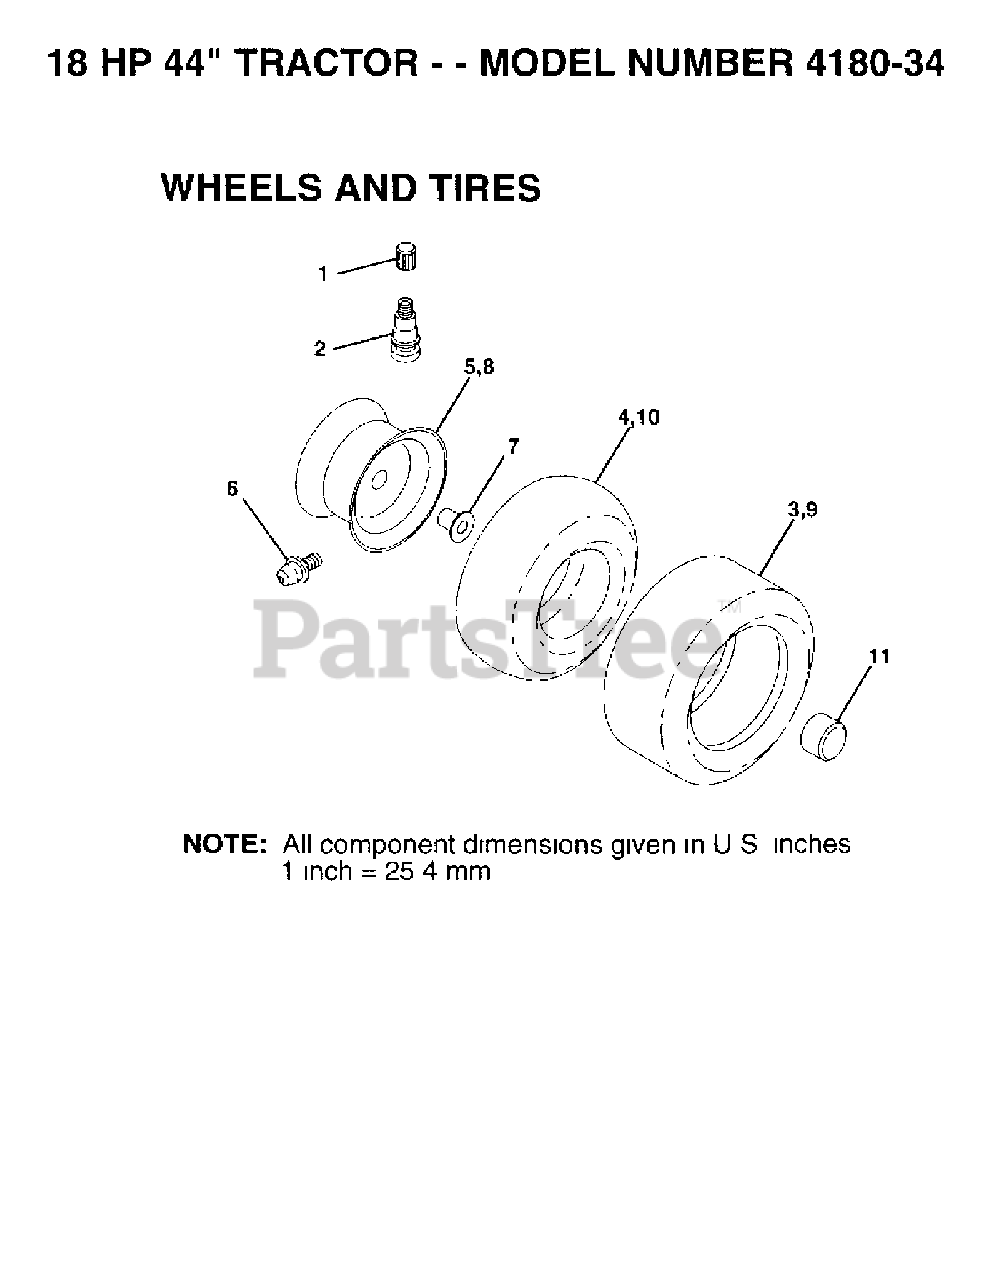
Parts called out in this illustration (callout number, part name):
1	VALVE CAP
2	VALVE STEM LT
3	TIRE HEAVY DUTY
4	TUBE.5.3/4.5/6
5	RIM.ASM.6".FRONT.SILVER
6	FITTING LT
7	BEARING T
9	Tire, .23 X 8.5-12 Turf Saver
10	TUBE.23"X9.5""X12""
11	CAP.HUB.FRONT.LT.BLACK
